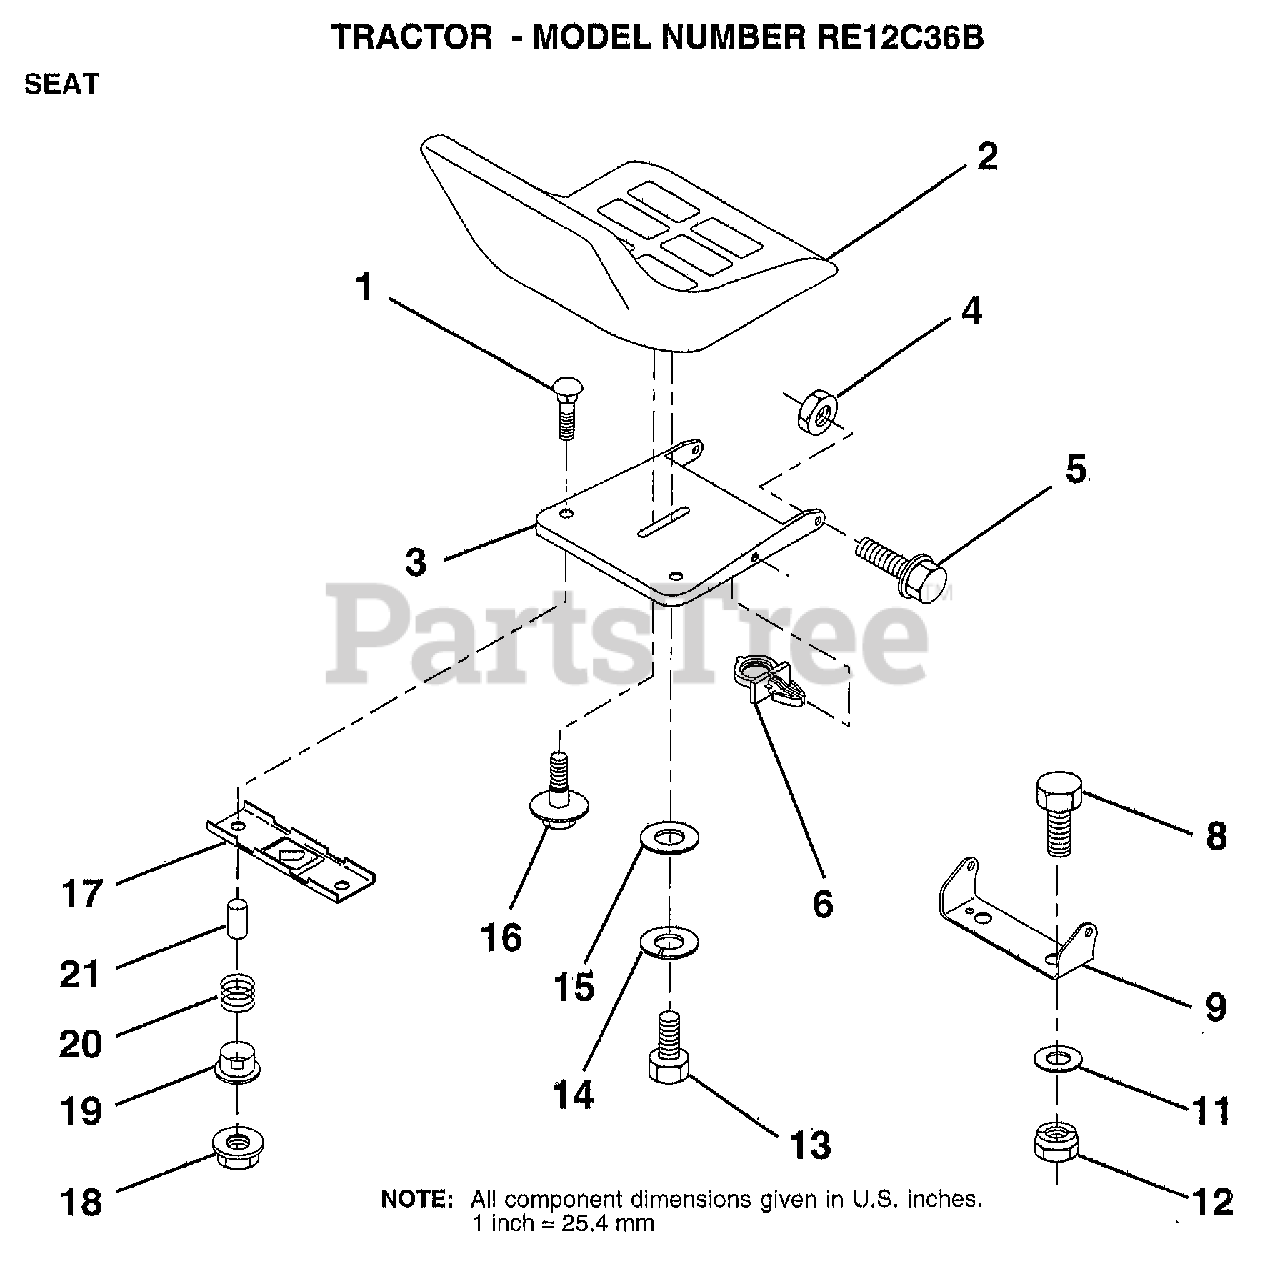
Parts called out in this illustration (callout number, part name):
1	BOLT-RD HD SQ NK
3	PAN-SEAT
4	NUT
5	"BOLT,SHOULDER"
6	CLIP.PUSH-IN.HING
8	BOLT
9	BRACKET PVT SEAT
11	WASHER
12	NUT
13	BOLT
14	LOCKWASHER
15	WASHER
16	"BOLT,SHOULDER"
17	BRKT SWITCH
19	BUSHING
20	SPRING
21	SPLIT SPACER
